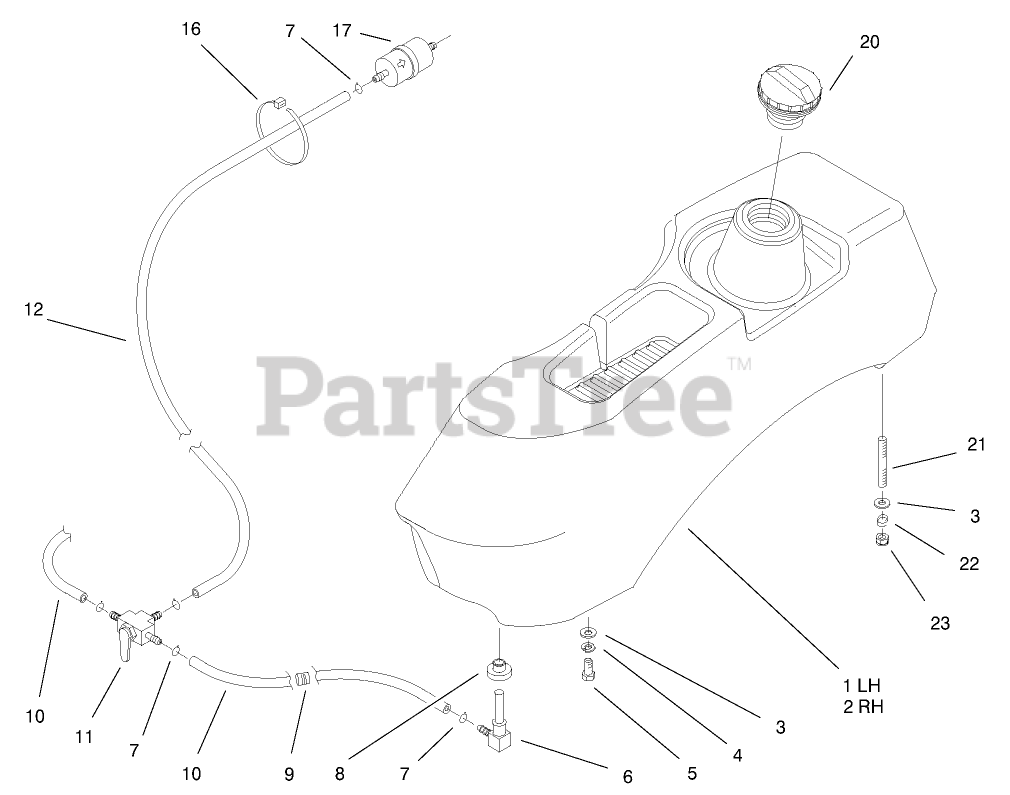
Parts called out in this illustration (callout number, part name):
1	TANK-FUEL, LH
2	TANK-FUEL, RH
3	WASHER-PLAIN
4	WASHER-LOCK
5	SCREW-HH
6	Elbow
7	Clamp
8	Bushing
9	Grommet-Fuel Line
10	Fuel Line
11	Valve-Fuel Line
12	Fuel Line
13	SCREW-HH
14	Clip
15	NUT-LOCK, NI
16	Tie-Plastic
17	Filter-Fuel
20	CAP-FUEL
21	Stud
22	Spring-Fuel Tank
23	NUT-LOCK, NI
